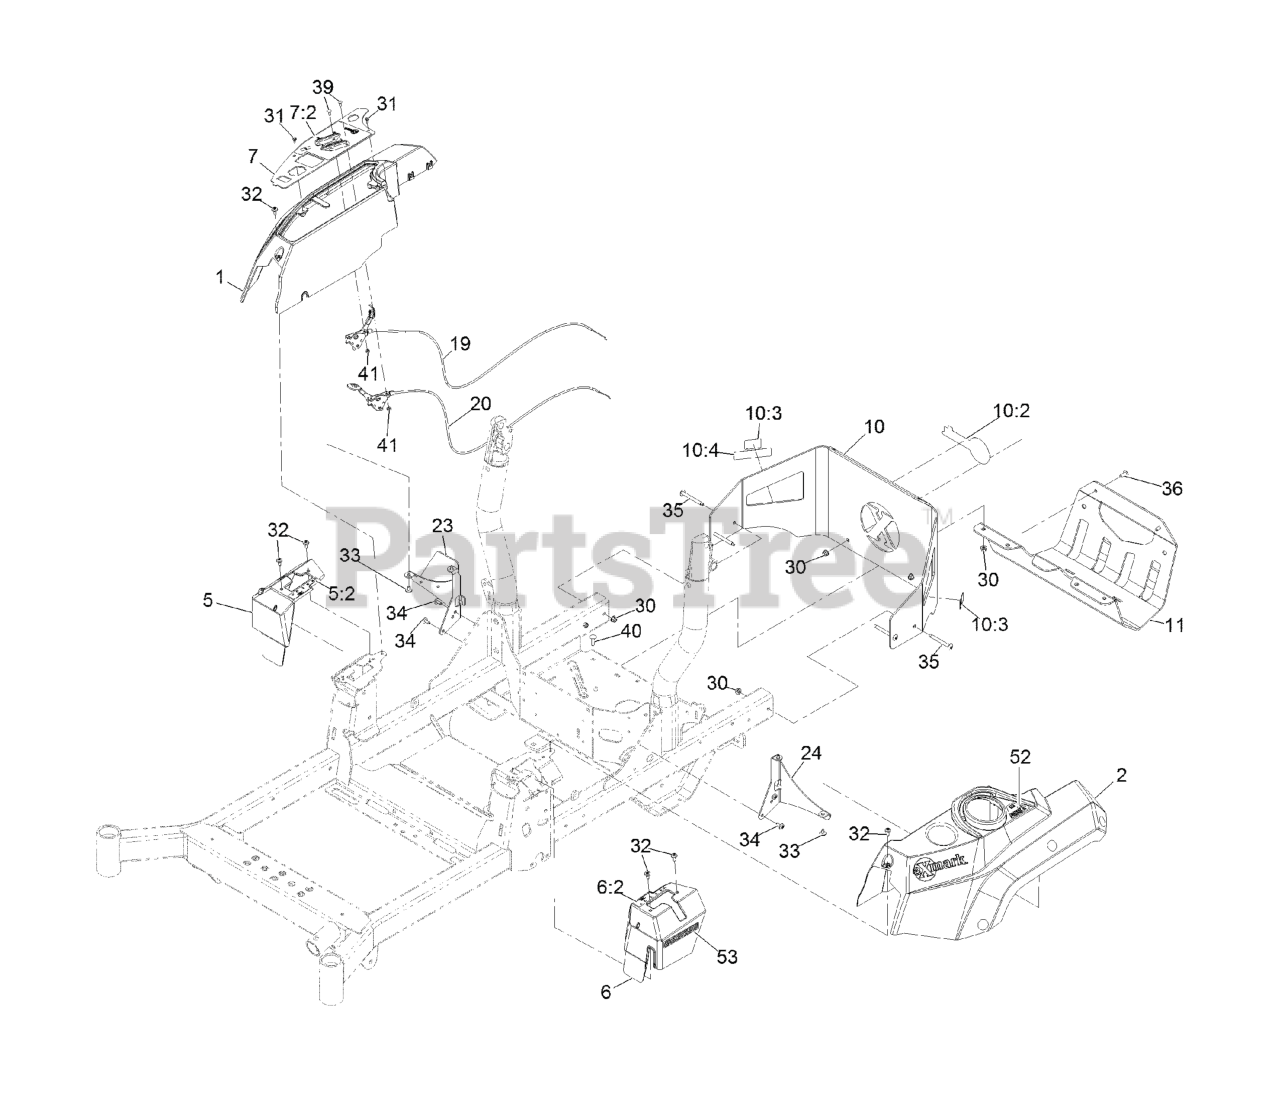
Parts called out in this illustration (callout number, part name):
1	CONSOLE, RH
2	CONSOLE, LH
5	COVER-CONTROL, MOTION (RH
5:2	Decal-Control, Motion (RH)
6	COVER-CONTROL, MOTION (LH
6:2	Decal-Control, Motion (LH)
7	CTRL PANEL ASM W/DECAL
7:2	DECAL-CONTROL PANEL
10	REAR GUARD ASM
10:2	DECAL-EXMARK LOGO
10:3	DECAL-WARNING
10:4	DECAL-ARRESTOR, SPARK
11	GUARD-MUFFLER
19	CABLE-CONTROL, CHOKE
20	CABLE-CONTROL, THROTTLE
23	SUPPORT-CONSOLE, RH
24	BRACKET-CONSOLE, LH
30	NUT-HF, NI
31	SCREW-HWH
32	SCREW-SHOULDER
33	SCREW-TORX
34	SCREW-TORX
35	SCREW-TORX
36	SCREW-TORX
39	BOLT-CARR
40	SCREW-CARR
41	NUT-LOCK, NI
52	DECAL-FILL, FUEL
53	DECAL-E-SERIES
